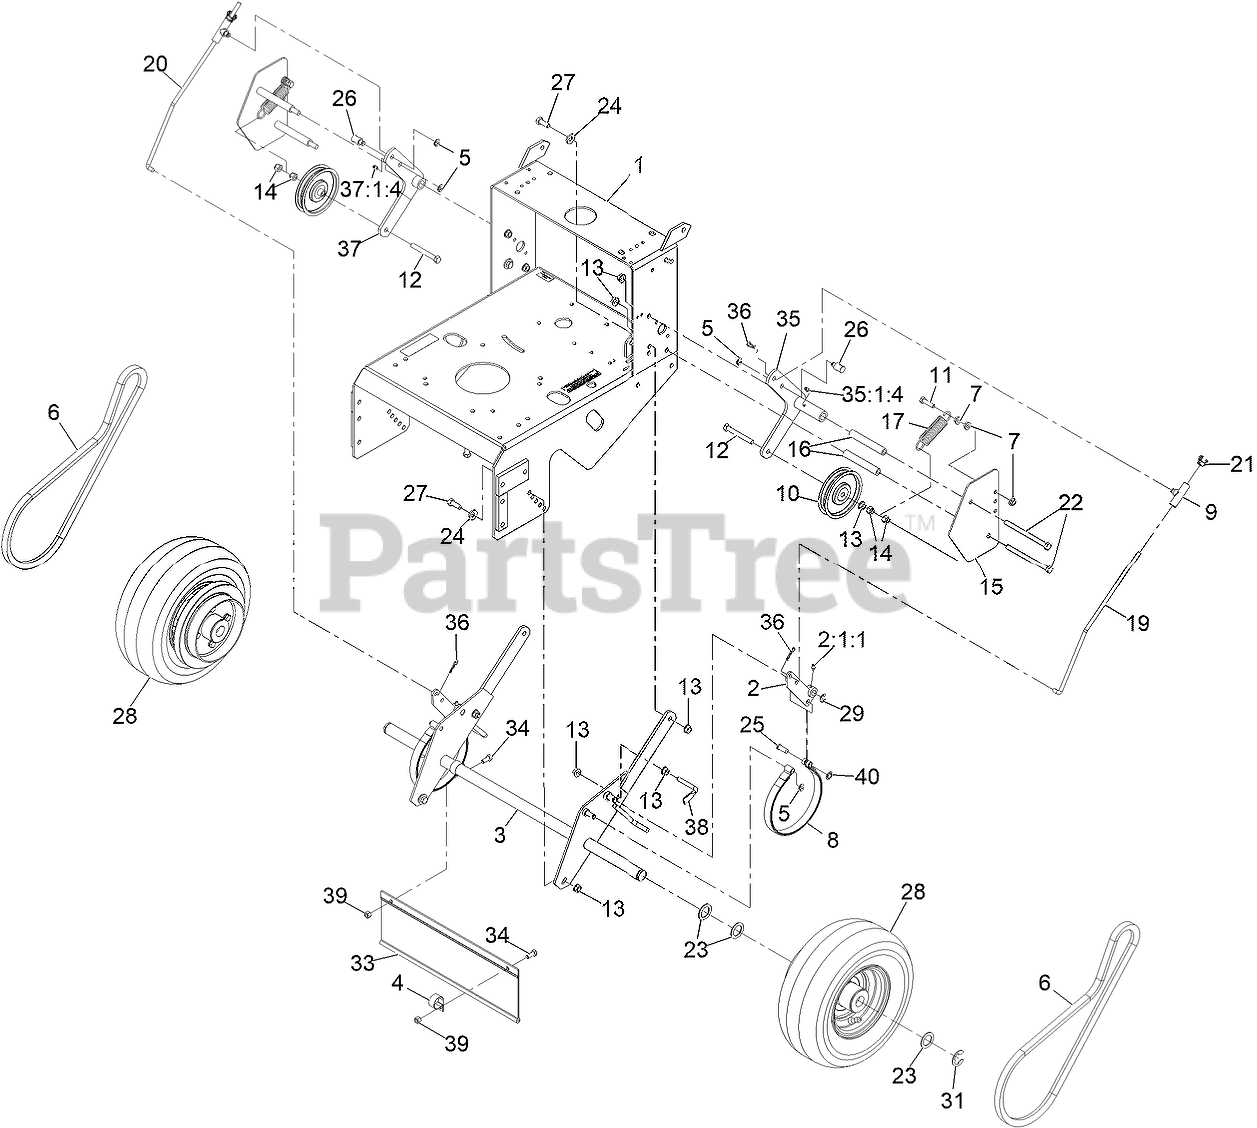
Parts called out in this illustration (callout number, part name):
1	ASM, METRO ENGINE DECK W/DECALS
2	ARM-BRAKE
2:1:1	BUSHING-ZERK
4	CLAMP-R
5	RING-RETAINING
8	BAND-BRAKE
9	SWIVEL-BRAKE
10	IDLER-WHEEL, DRIVE
11	SCREW-HH, SPECIAL
12	SCREW-HH
13	NUT-HHF, WHIZ
14	NUT-LOCK, NI
15	SHIELD-WHEEL, DRIVE
16	SPACER-SHIELD
17	SPRING-EXTENSION
19	LINKAGE-BRAKE, LH
20	LINKAGE-BRAKE, RH
21	WINGNUT-NYLOCK
22	SCREW-HH
23	WASHER-SPACER
24	WASHER-BELLEVILLE
25	PIN-CLEVIS
26	SWIVEL-DRIVE LEVER, 3/8 LH
27	SCREW-HH
28	DRIVE WHEEL ASM
29	RING-RETAINING, EXTERNAL
31	RING-SNAP
33	SHIELD-TRAILING
34	SCREW-HH
35	ARM-IDLER, LH
35:1:4	FITTING-GREASE
36	PIN-COTTER
37	ARM-IDLER, RH
37:1:4	FITTING-GREASE
38	SCRAPER
39	NUT-LOCK, NI
40	RING-RETAIN,PUSH,EXT,FLAT
